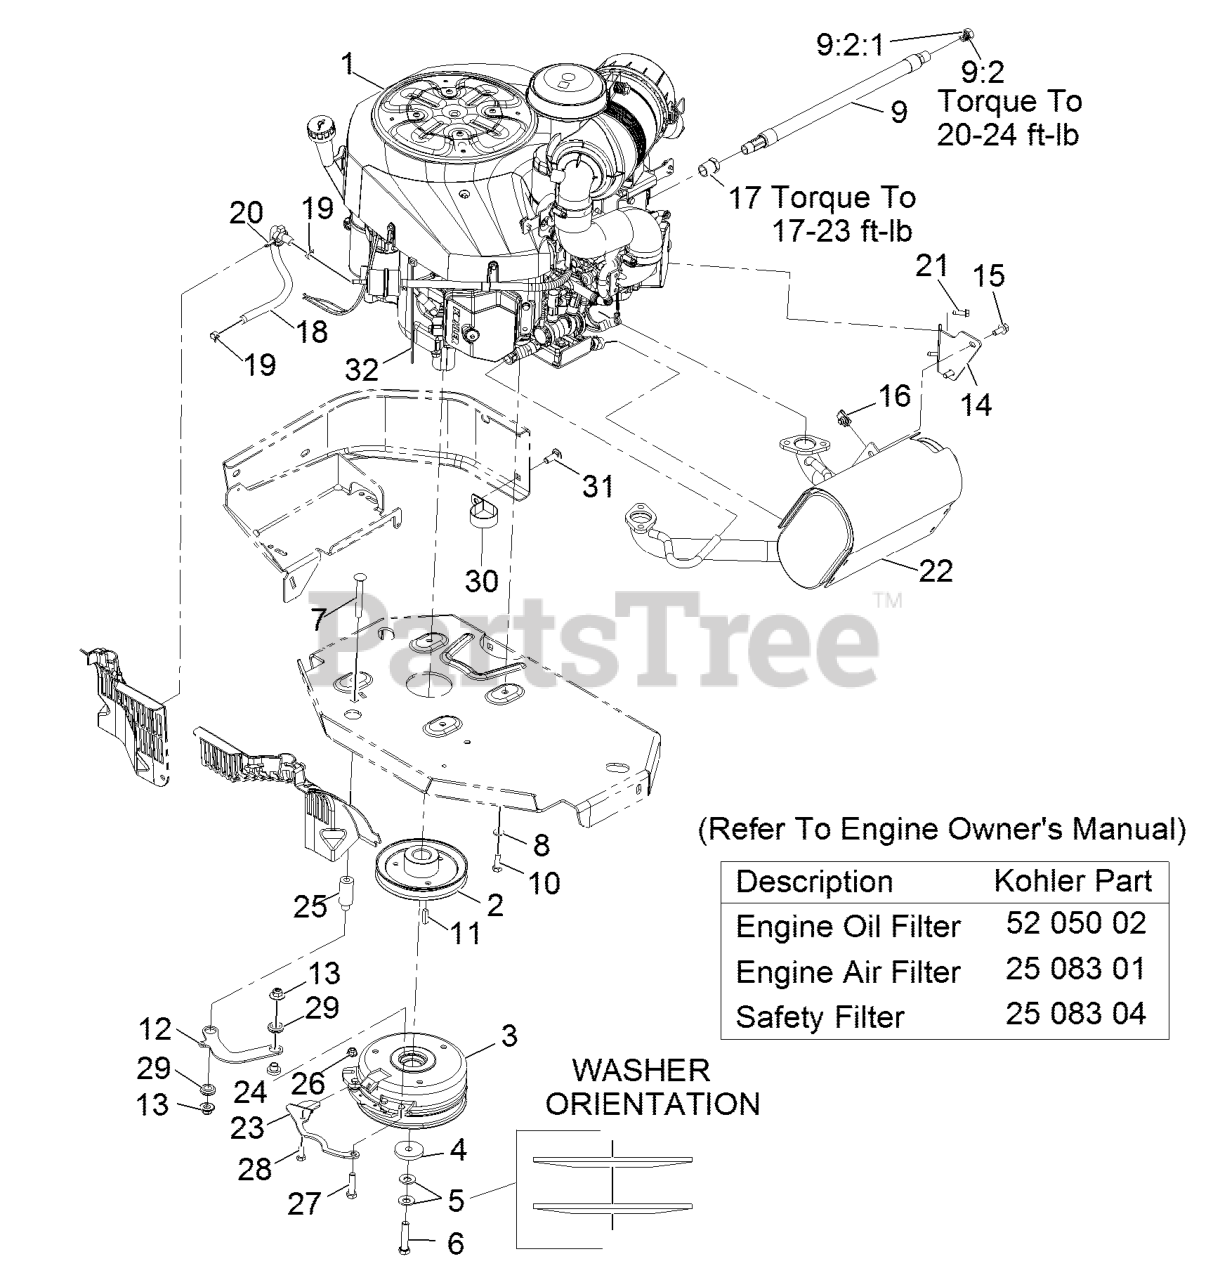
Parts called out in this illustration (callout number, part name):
1	Engine-Kohler
2	SHEAVE
4	WASHER-CLUTCH
5	WASHER-SPRING
6	SCREW-HH W/LOCTITE
7	SCREW-CARR
8	WASHER-SPRING
9	OIL DRAIN HOSE ASM
9:2	PLUG-HH
9:2:1	O-RING
10	SCREW-HH
12	LINK-ANCHOR, CLUTCH
13	Nut-Nyloc 3/8-16 Flg
15	SCREW-HHF
17	BUSHING
19	CLAMP-HOSE
20	CLAMP-HOSE
22	MUFFLER, KC BIG BLOCK AIS
23	BELT-GUIDE
26	NUT-HF, NI
27	SCREW-HH
28	SCREW-HH
29	GROMMET-RUBBER
30	CLAMP-R
31	SCREW-CARR
32	TIE-PLASTIC
